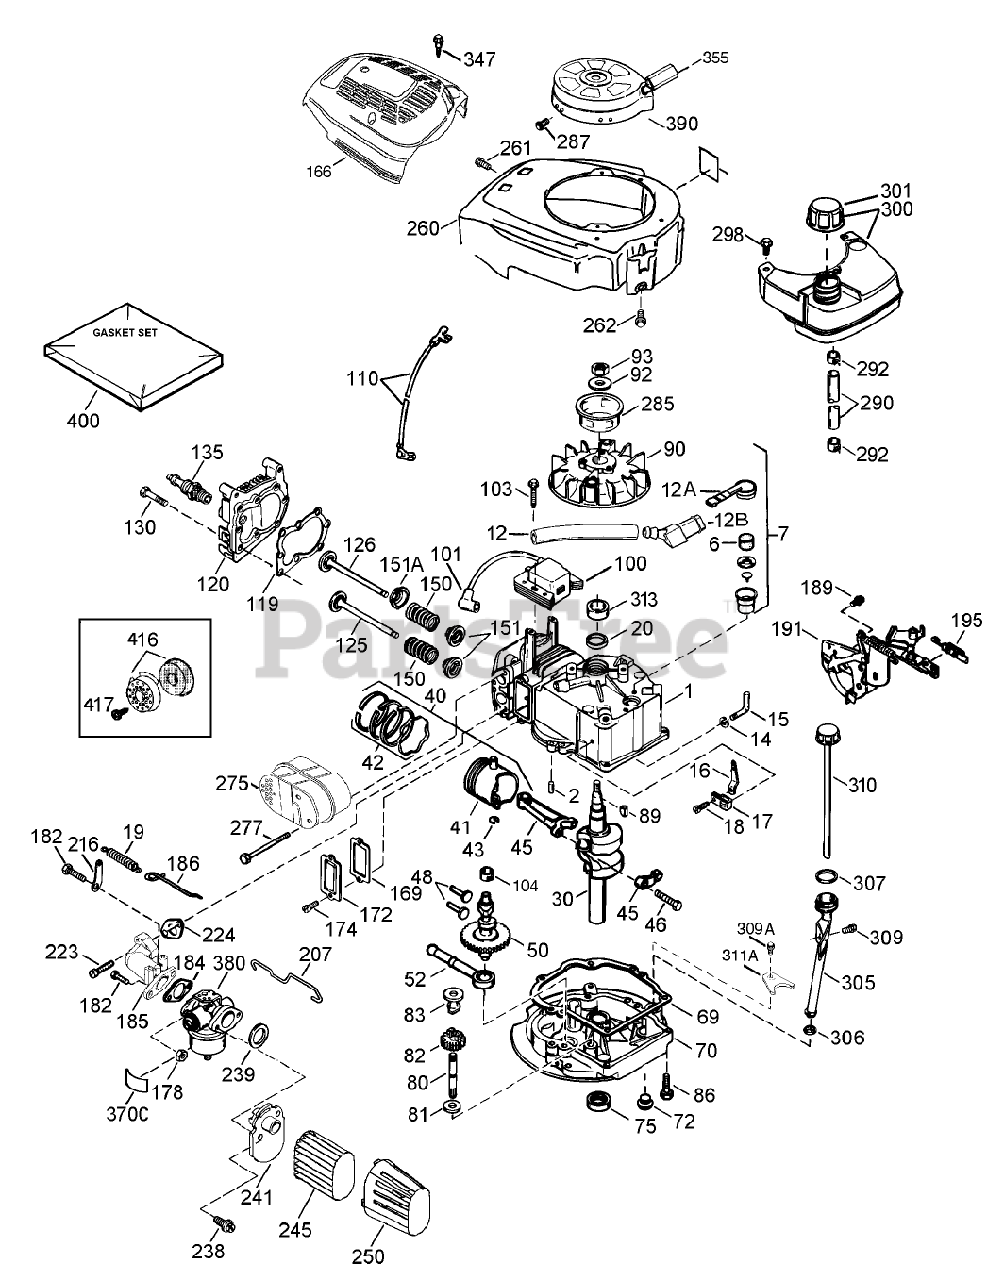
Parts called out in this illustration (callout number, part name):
1	Cylinder ASM
2	Pin-Dowel
6	Element-Breather
7	Breather ASM (Incl. Ref. #6 and 12A)
12	Tube-Breather
12A	Breather Cover and Tube (Incl. Ref. #12B)
12B	Elbow-Tube, Breather
14	Washer-Flat
15	Rod, Governor (Incl. No. 36)
16	Lever-Governor
17	Clamp-Lever, Governor
18	Screw (T-15, 8-32 x 19/64)
19	Spring-Extension
20	Seal-Oil
30	Crankshaft
40	Piston, Pin and Ring Set (Std.)
41	Piston and Pin ASM (Std.) (Incl. Ref. # 43)
42	FITTING - TANK 3/4"
43	Ring-Retaining, Piston Pin
45	Connecting Rod ASM (Incl. Ref. #46)
46	Bolt-Rod, Connecting
48	Lifter-Valve
50	Camshaft (Exhaust MCR) (Incl. Ref. #104)
52	Oil Pump ASM
69	Gasket-Flange, Mounting
70	Flange-Mounting (Incl. Ref. #72-83,306,309A 311A)
72	Plug-Drain, Oil
75	Seal-Oil
80	Shaft-Governor
81	Washer-Flat
82	Governor Gear ASM
83	Spool-Governor
86	Screw (1/4-20 x 1-1/4)
89	Key-Flywheel
90	Flywheel
92	Washer-Belleville
93	Nut-Flywheel
100	Ignition-State, Solid
101	Cover-Spark Plug
103	Screw (T-15, 10-24 x 15/16)
104	Bushing-Cam
110	Wire-Ground
110A	Wire ASM
110B	Wire ASM
119	Gasket-Cylinder Head
120	Head-Cylinder
125	Valve-Exhaust (1/32in OS) (Incl. 151)
125	Valve-Exhaust (Std.) (Incl. Ref. #151)
126	Valve-Intake (Std.) (Incl. Ref. #151 and 151A)
130	Screw (5/16-18x1-1/2)
135	Spark Plug-Resistor (R J19 L M)
150	Spring-Valve
151	Cap-Valve, Spring
151A	BEARING - TRANS
166	Shroud-Engine
169	Gasket-Cover, Valve
172	Cover-Valve
174	Screw (10-24 x 9/16)
178	Nut and Lock Washer (1/4-28)
184	Gasket
185	Pipe-Intake
186	Link-Governor
189	Screw, 1/4-20 x 3/8"
191	S.E. Brake Bracket (Incl. 195)
195	Terminal
196	Switch-Restart, Power
207	Link-Throttle
216	Lever-Adjusting, R P M
223	Screw (1/4-20 x 1)
224	Gasket-Pipe, Intake
238	Screw (10-32 x 49/64)
239	Gasket-Cleaner, Air
241	Collar-Cleaner, Air
245	Filter-Cleaner, Air (Paper)
250	Cover-Cleaner, Air
260	Blower Housing
261	Screw (10-24 x 9/16)
262	Screw (1/4-20 x 1/2)
275	Muffler
277	Screw (1/4-20 x 2-9/32)
285	Cup-Starter
287	Screw (8-32 x 21/64)
290	Line-Fuel (8.62)
292	Clamp-Line, Fuel
298	Screw (10-32 x 35/64)
300	Fuel Tank (Incl. Ref. #292 and 301)
301	Cap-Fuel
305	Oil Fill Tube (Incl. 306)
306	O-Ring
307	O-Ring
309	Screw (10-32 x 1/2)
309A	Screw (10-24 x 3/4)
310	Dipstick
311A	Bracket-Holddown
313	Spacer
325	Clip-Actuator, Brake Switch
347	Screw (10-32 x 27/32)
370C	Decal-Primer
370D	Decal-Warning
380	Carburetor (Incl. Ref. #184 of Engine Parts List)
390	Rewind Starter ASM
395	Electric Starter
400	Gasket Set
416	Spark Arrestor Kit (Incl. 417)(Optional)
417	Screw (8-32 x 3/8)
